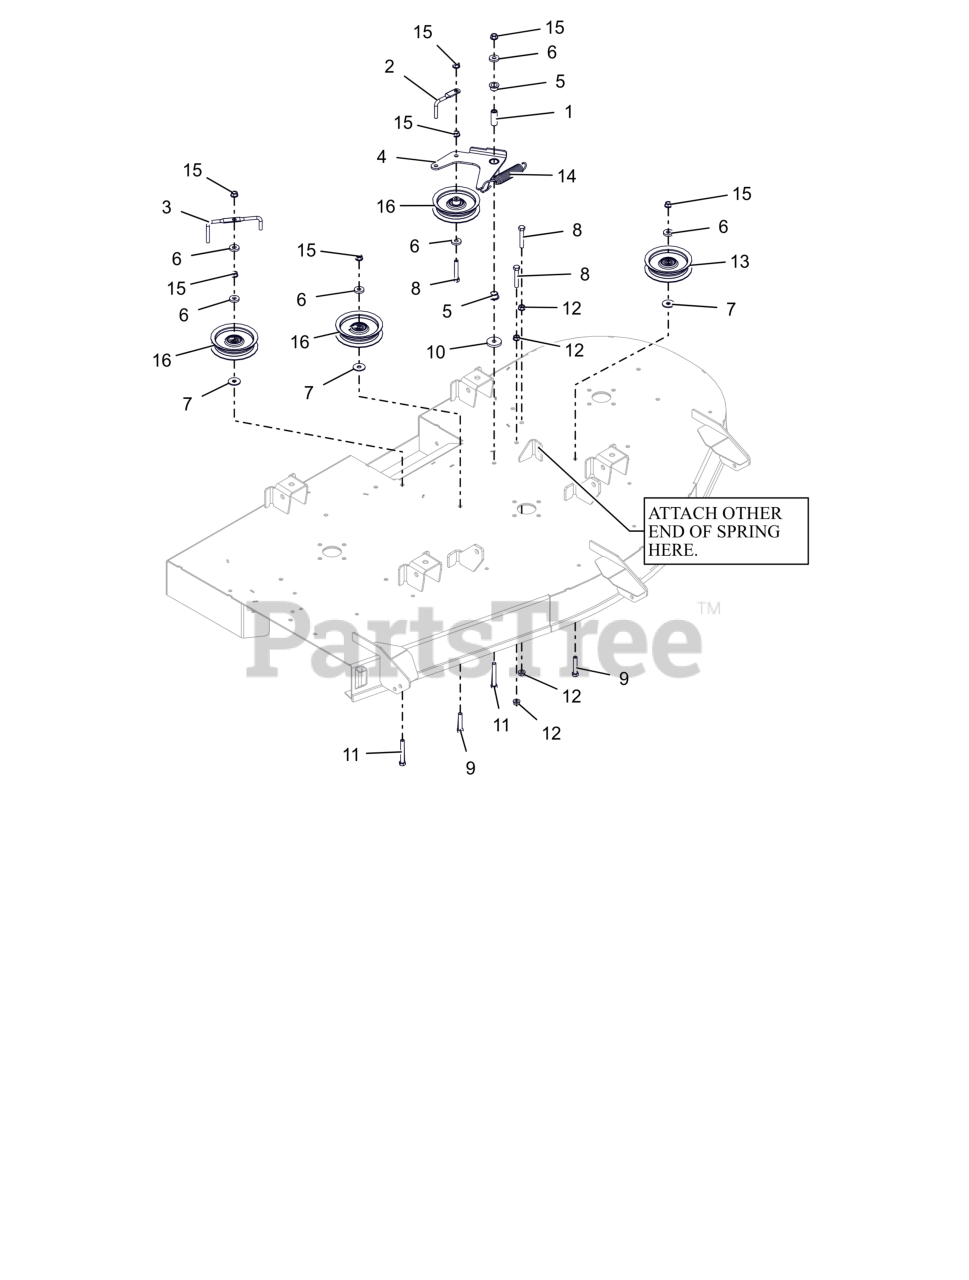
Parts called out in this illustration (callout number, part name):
1	SPACER, .375IDX.625ODX1.66 PM
2	WIREFORM-BELT FINGER
3	BELT FINGER
4	WLDMT, IDLER ARM-42"
5	BSHG-FLG, .625X.750X.500X1.00
6	WSHR, FLT .406X1.00X.188 ZCC
7	WSHR FL STL .406X1.25X.10ZC120
8	BLT,HEX .38-16X2.25 G5 ZCC
9	BLT,HEX .38-16X2.00 G5 ZCC
10	WSHR, FLT .406X1.50X.245 ZCC
11	BLT, HEX .38-16X2.75 G5 ZCC
12	NUT, SPNLK-FLG .38-16 G5 ZCC
13	IDLER, FLAT - 4.06" X .75"
14	SG-TENS .135X.98X6.0 WLD 62
15	NUT-LK-CTR-FLG .375-16 GF ZCC
16	IDLER, FLAT - 4.06" X .75"
